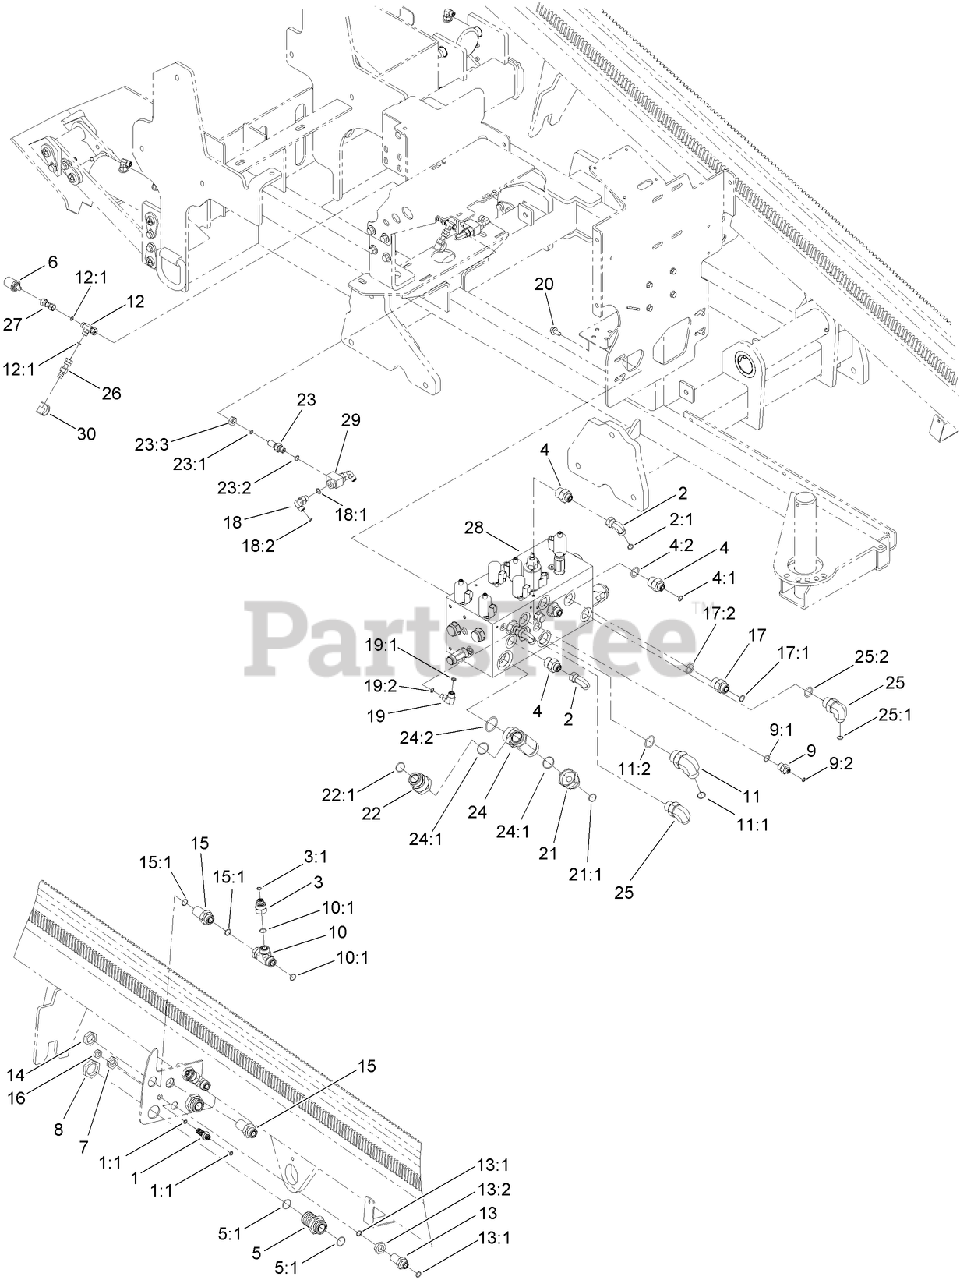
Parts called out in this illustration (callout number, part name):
1	UNION-BULKHEAD
1:1	O-RING
2	FITTING-HYD
2:1	O-RING
3	FITTING-HYD
3:1	O-RING
4	FITTING-STR
4:1	O-RING
4:2	O-RING
5	ADAPTER-HYD
5:1	O-RING
6	TRANSDUCER
7	NUT-BULKHEAD
8	NUT-BULKHEAD
9	FITTING-STR
9:1	O-RING
9:2	O-RING
10	FITTING-HYD, TEE
10:1	O-RING
11	FITTING-ELBOW 90
11:1	O-RING
11:2	O-RING
12	FITTING-HYD
12:1	O-Ring
13	FITTING-BULKHEAD
13:1	O-RING
13:2	NUT-BULKHEAD
14	NUT-LOCK, BULKHEAD
15	FITTING-BULKHEAD UNION, STRAIGHT
15:1	O-RING
16	NUT-LOCK
17	FITTING-STRAIGHT
17:1	O-RING
17:2	O-RING
18	FITTING-ELBOW 90
18:1	O-RING
18:2	O-RING
19	FITTING-ELBOW 90
19:1	O-RING
19:2	O-RING
20	SCREW-HHF
21	FITTING-STRAIGHT
21:1	O-RING
22	FITTING-REDUCER
22:1	O-RING
23	FITTING-STRAIGHT
23:1	O-RING
23:2	O-RING
23:3	NUT-LOCK
24	FITTING-TEE
24:1	O-RING
24:2	O-RING
25	FITTING-HYD, 90 DEG
25:1	O-RING
25:2	O-RING
26	NIPPLE-TEST
27	FITTING-STRAIGHT
28	4 SECTION HYD VALVE ASM
29	VALVE-SHUTTLE, LOAD
30	CAP-DUST
